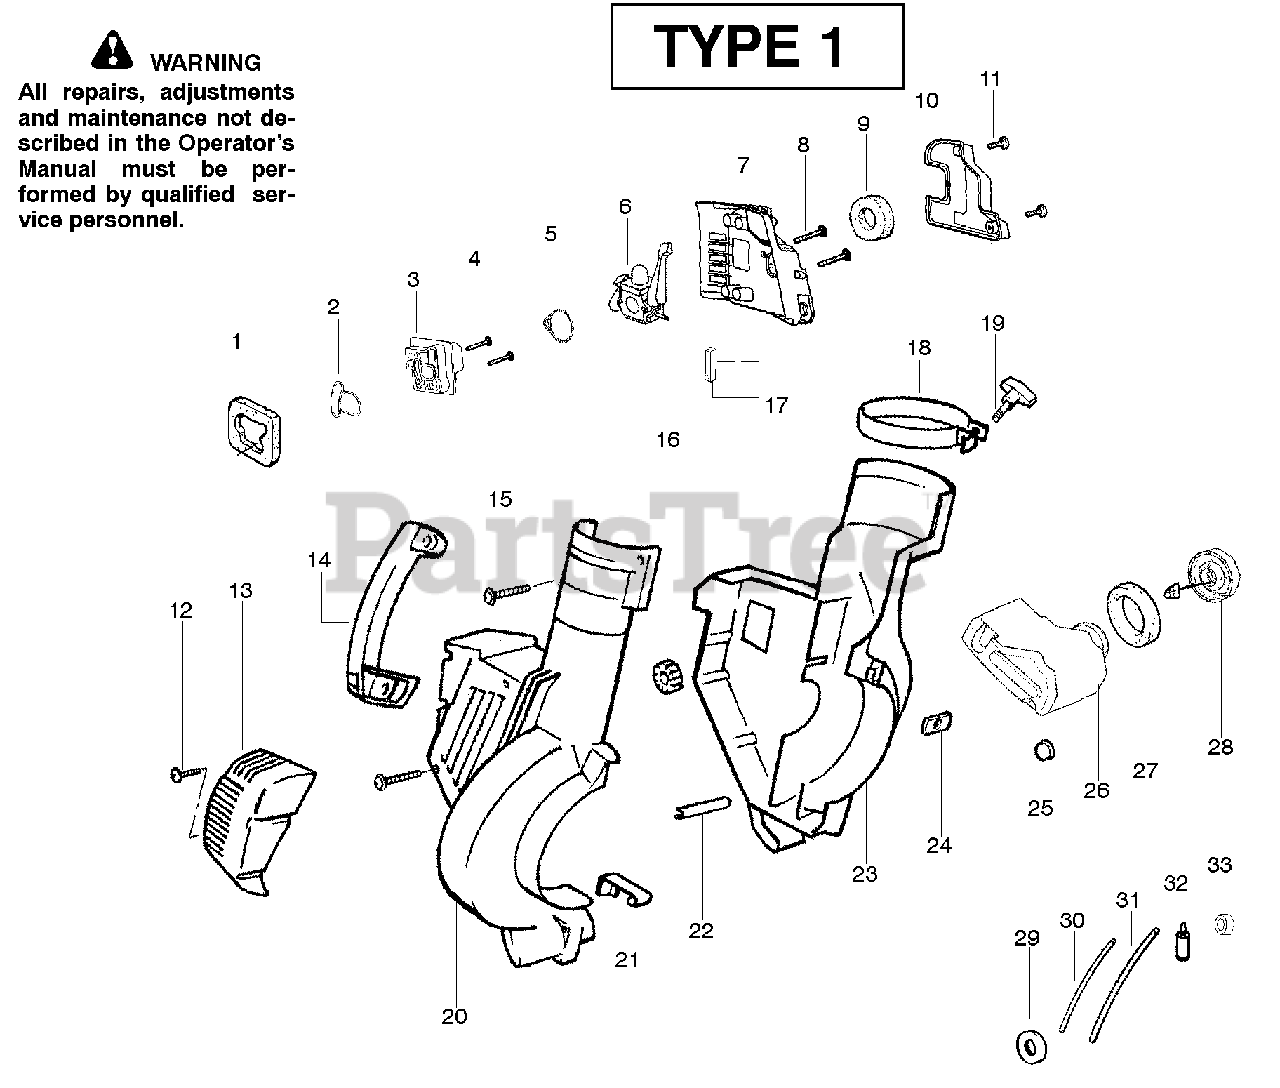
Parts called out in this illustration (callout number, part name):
1	Air Dam (kit)
2	Gasket-Adapter (kit)
3	Carburetor Adaptor
5	Gasket-Carburetor (kit)
6	Kit-Carb Ass'y. (C1Q-W11)
8	Screw-Carb.
9	Filter-Air
10	Cover-Air Filter
11	Screw-Air Box Cover
13	Assy-Muffler Cover
16	Isolator
17	Foam 25.4mm (kit)
18	Clamp-Blower Tube
19	Knob-Tube Clamp
20	Housing-Right
21	Spring-Cover Latch
22	Guide-Starter Rope
23	Housing-Left
25	Isolator-Crankcase
26	Assy-Fuel Tank
27	Gasket-Fuel Tank
28	Fuel Cap w/Retainer
29	Grommet-Shroud
30	Kit-Line Carb/Purge
31	Kit-Line Tank/Purge
32	Assy-Fuel Pick-up
33	Grommet-Fuel line (kit)
